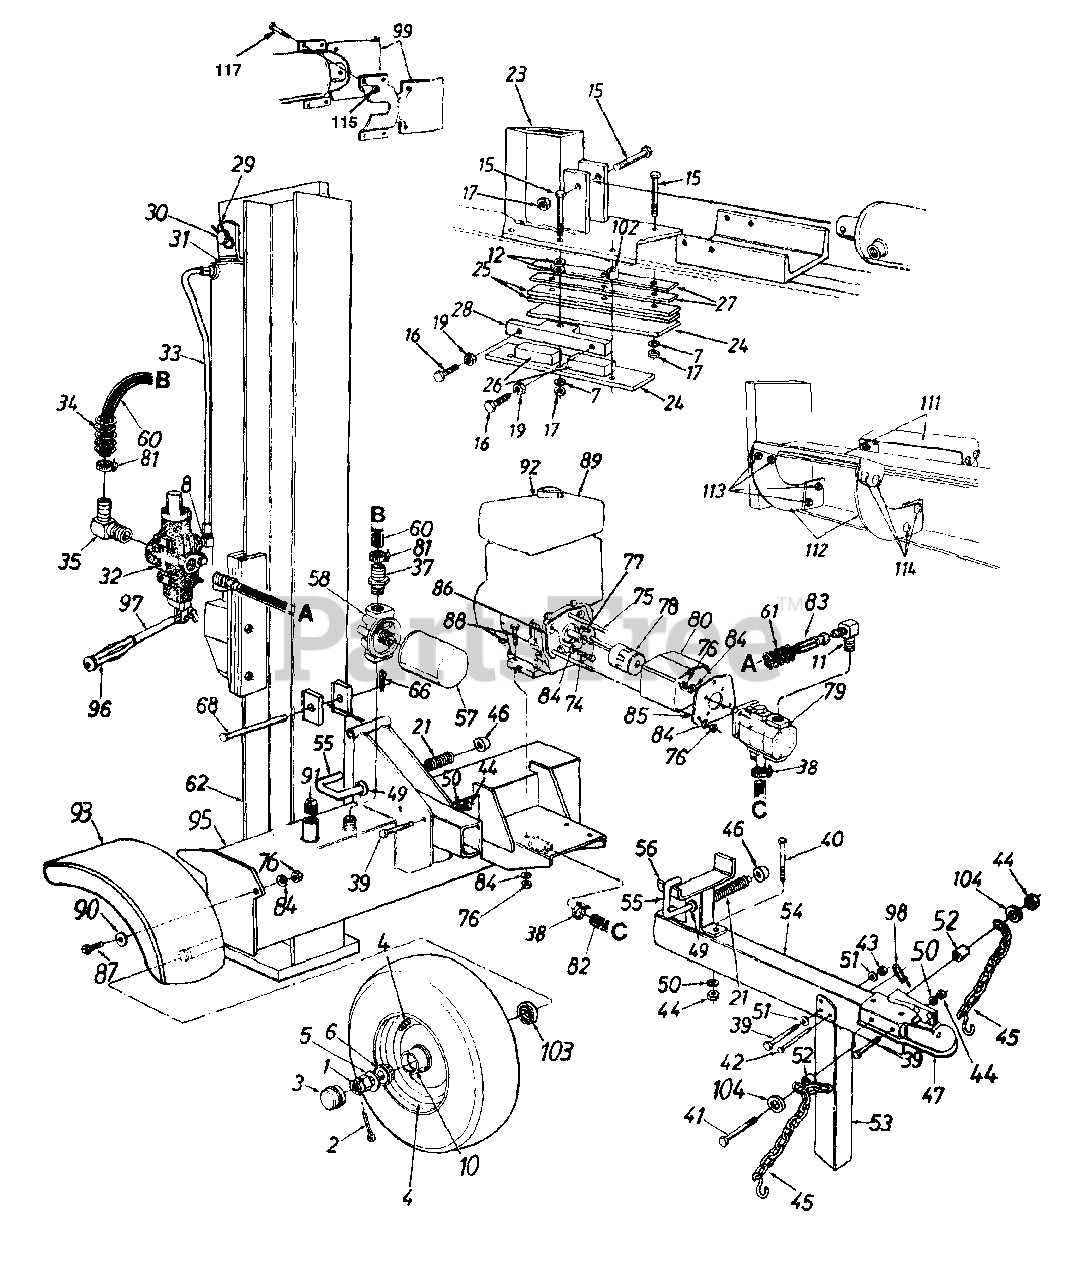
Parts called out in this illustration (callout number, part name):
1	Slotted Nut 3/4-16 Thd.
2	Cotter Pin 5/32" Dia.
5	Fl-Wash..76" I.D. x 1.5" O.D.
6	Bearing Cone
7	L-Wash. 1/2" I.D.
10	Bearing Cup
11	90 degree Male Adapter
12	Fl-Wash. .531" I.D. x .94" O.D.
15	Hex Bolt 1/2-20 x 2.75" Lg. (Grade 8)
16	Hex Bolt 3/8-24 x 1.5" Lg.
17	Hex L-Nut 1/2-20 Thd.
19	Hex Jam Nut 3/8-24 Thd. (Grade 5)
21	Comp. Spring 4" Lg.
23	Wedge Ass'y.
26	Adjustable Gib
29	Cotter Pin
30	Clevis Pin
31	Hydraulic Cylinder
32	Control Valve
33	Metal Pressure Tube
34	Hose Guard
35	Return Elbow
37	3/4" Hose Barb.
38	Hose Clamp 1.5" O.D.
39	Hex Bolt 3/8-16 x 3" Lg. (Grade 8)
40	Hex Bolt 3/8-16 x 4" Lg.
41	Hex Bolt 3/8-16 x 4.25" Lg.
42	Clevis Pin 5/16 x 2.5" Lg.
43	Hex L-Nut 3/8-16 Thd.
44	Hex Nut 3/8-16 Thd.
45	Chain - Tow Hitch
47	Hitch Coupler
49	Fl-Wash. .635" I.D. x .93" O.D.
50	L-Wash. 3/8" I.D.
51	Fl-Wash. .406" I.D. x .75" O.D.
52	Spacer .445" Lg.
54	Tongue Tube
55	Locking Rod
56	Beam Support Ass'y.
57	Filter Element
58	Filter Head
60	Return Hose 3/4" I.D. x 44" Lg.
61	Nose Guard
62	Vertical Beam Weldment
66	Cotter Pin 1/8" Dia.
68	Hinge Pin 1/2 x 4.8" Lg.
74	Hex Bolt 5/16-24 x .62" Lg.
75	Hex Bolt 5/16-24 x 5.25" Lg.
76	Hex Nut 5/16-24 Thd.
77	Sq.-Key 1/4" x 2" Lg.
78	Flexible Coupling
79	Gear Pump
80	Coupling Shield
81	Hose Clamp 5/8"
82	Suction Hose 1" I.D.
83	High Pressure Hydraulic Hose 48"
84	L-Wash. 5/16" I.D.
87	Hex Bolt 5/16-24 x .75" Lg.
88	Hex Bolt 5/16-24 x 1.75" Lg.
89	Engine
90	Fl-Wash. .344" I.D. x .875" O.D.
91	L-Vent Pipe Plug
92	Spark Plug Boot
95	Frame Weldment
96	Grip
97	Control Handle
98	Spring Pin
102	Spacer 1/2" I.D. x .86" Lg.
103	Bearing Seal Only
104	Fl-Wash. 3/8" I.D. x .87" O.D.
111	Log Cradle
112	Cradle Support Brkt.
113	Flanged Lock Nut 3/8-16 Thd.
114	Carriage Bolt 3/8-16 x 1" Lg.
115	Hex L-Nut 3/8-16 Thd.
117	Hex Bolt 3/8-16 x 2.0" Lg. (Gr. 5)
